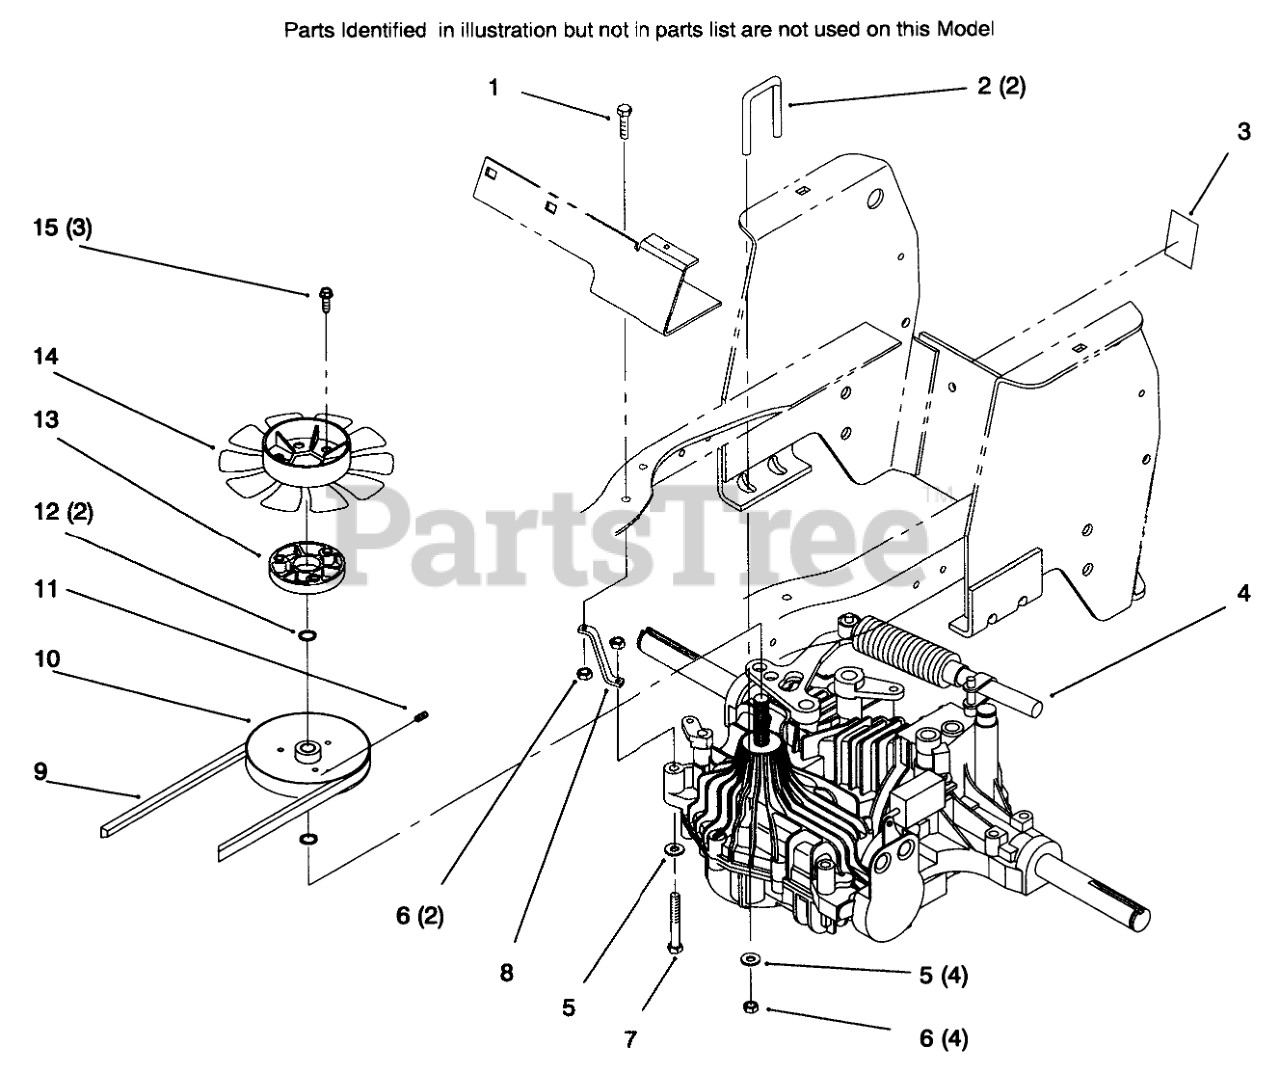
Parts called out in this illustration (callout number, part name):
1	SCREW-HH
2	U-BOLT
3	Decal-Hydro Valve (Only On: 72085)
3	Decal-Bypass (Only On: 72104)
4	TRANSAXLE - HYDROSTATIC
5	WASHER-PLAIN
6	NUT-LOCK, NI
7	SCREW-HH
8	STRAP-TRQ HY
9	Belt-Hydro
10	PULLEY-HYDRO TRANS
11	SCREW-HSH
12	SNAP RING
13	SPACER - FAN
14	FAN - HYDRO
15	SCREW-HWHTF
